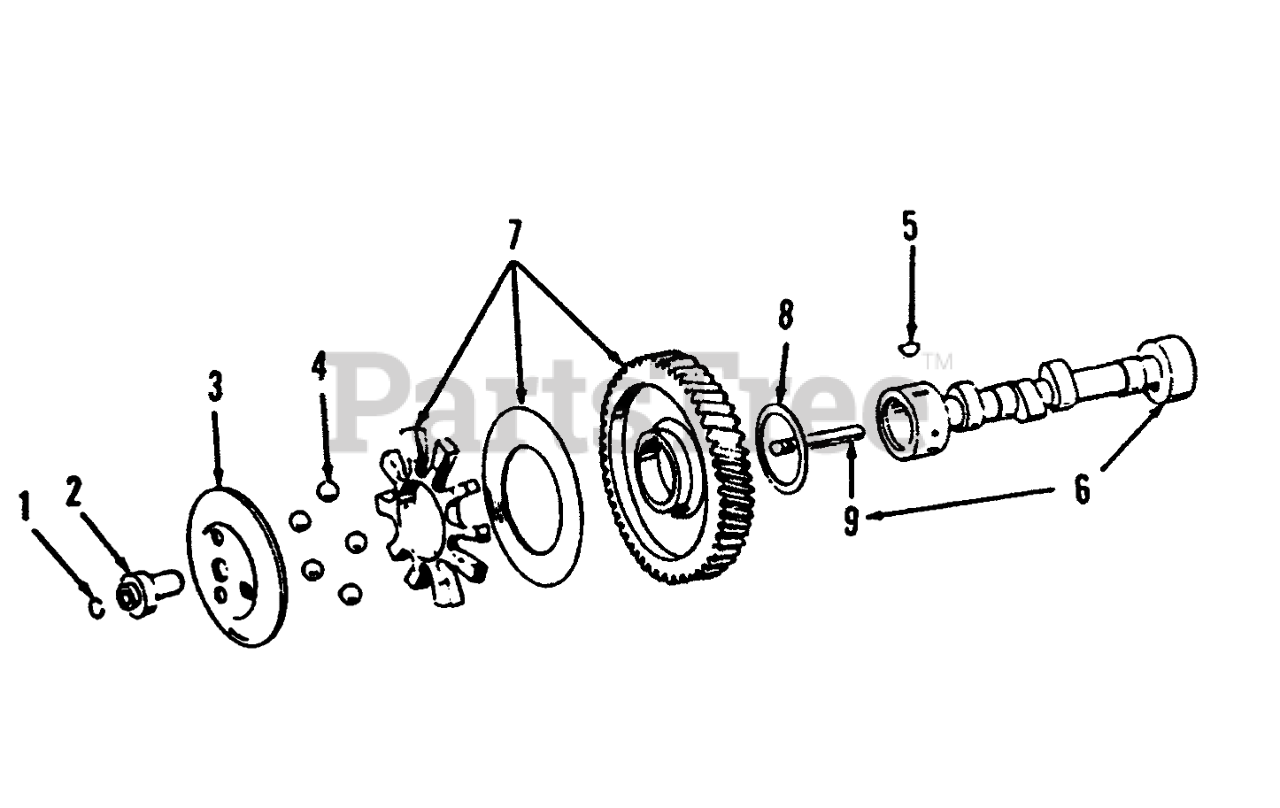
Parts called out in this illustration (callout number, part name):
2	HUB-GOVERNOR CUP
3	CUP-GOVERNOR
4	Ball
6	Camshaft (Includes Center Pin)
7	Gear-Camshaft (Includes Gear, Spacer, & Plate)
8	Washer
9	Pin
